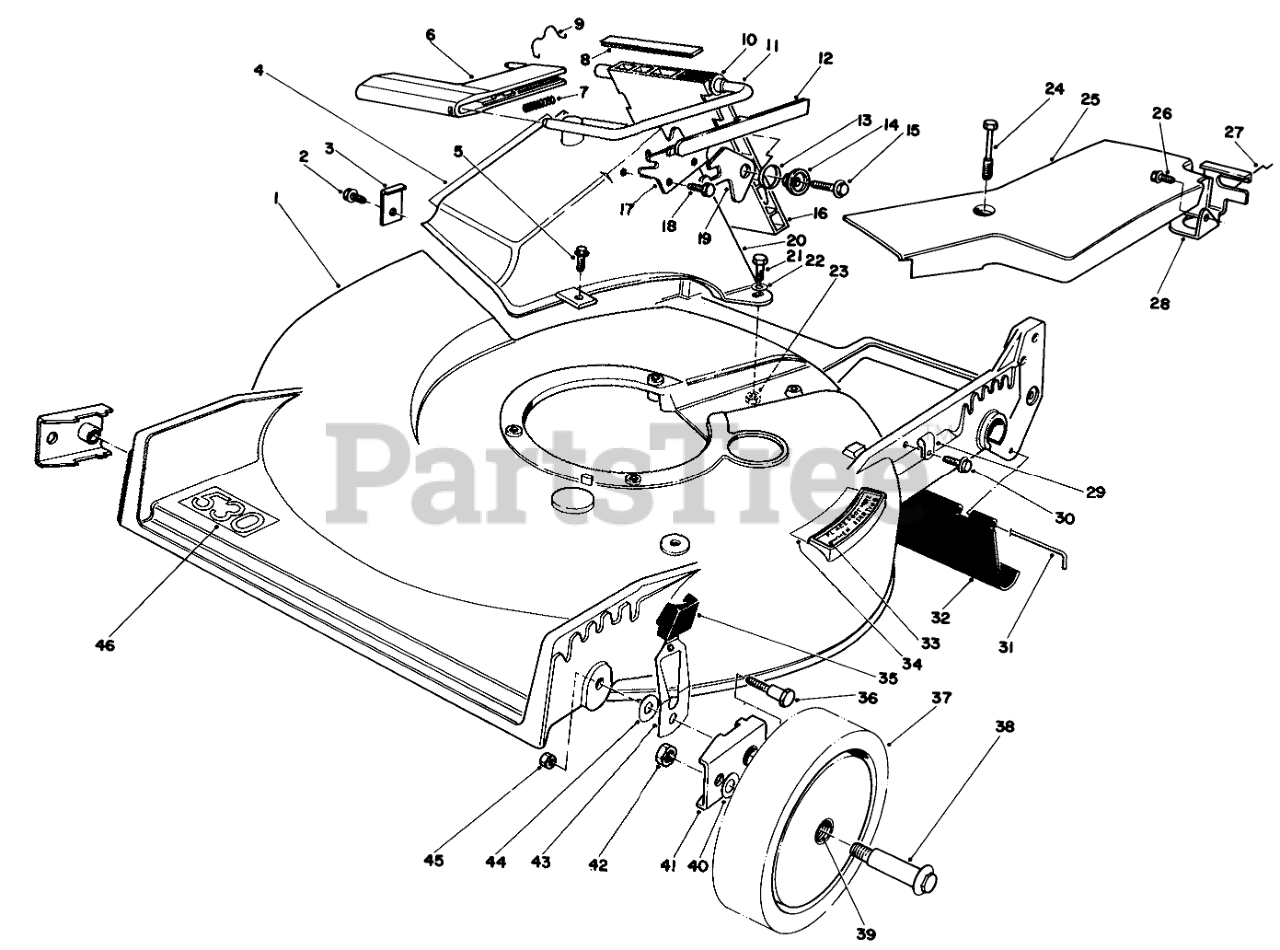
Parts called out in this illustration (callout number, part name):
1	BELT TENSIONER KIT
2	SCREW
3	TUNNEL CLIP
4	Decal-Attention
5	Screw
6	Handle-Door
7	Spring
8	Cover-Door
9	DOOR RET SPRING
10	Bushing
11	DOOR ROD +
12	DOOR HANDLE COVER
13	TORSION SPRING
14	DOOR SPACER
15	SCREW-HWH
16	Door Discharge
17	DOOR LATCH PLATE
18	SCREW-PLASTITE
19	SAFETY LATCH
20	Tunnel Discharge
21	SCREW-HH
22	WASHER-FLAT
23	NUT-LOCK, NI
24	SCREW-HHFTF
25	Cover-Belt
26	SCREW-HWHTF
27	RETAINER-CABLE
28	Bracket-Traction Adj.
29	CLAMP-CABLE
30	SCREW
31	ROD-SHIELD
32	SHIELD-TRAILING
33	STEP PAD DECAL
34	Decal-Place Foot Here
35	KNOB-ARM
36	PIVOT SCREW
37	Wheel 8 Tire Assembly
38	BOLT-WHEEL
39	BUSHING
40	WASHER
41	HP PIVOT ARM ASM
42	Nut
43	Spring Arm
44	WASHER-PIVOT
45	NUT-LOCK, NI
46	Decal-530
